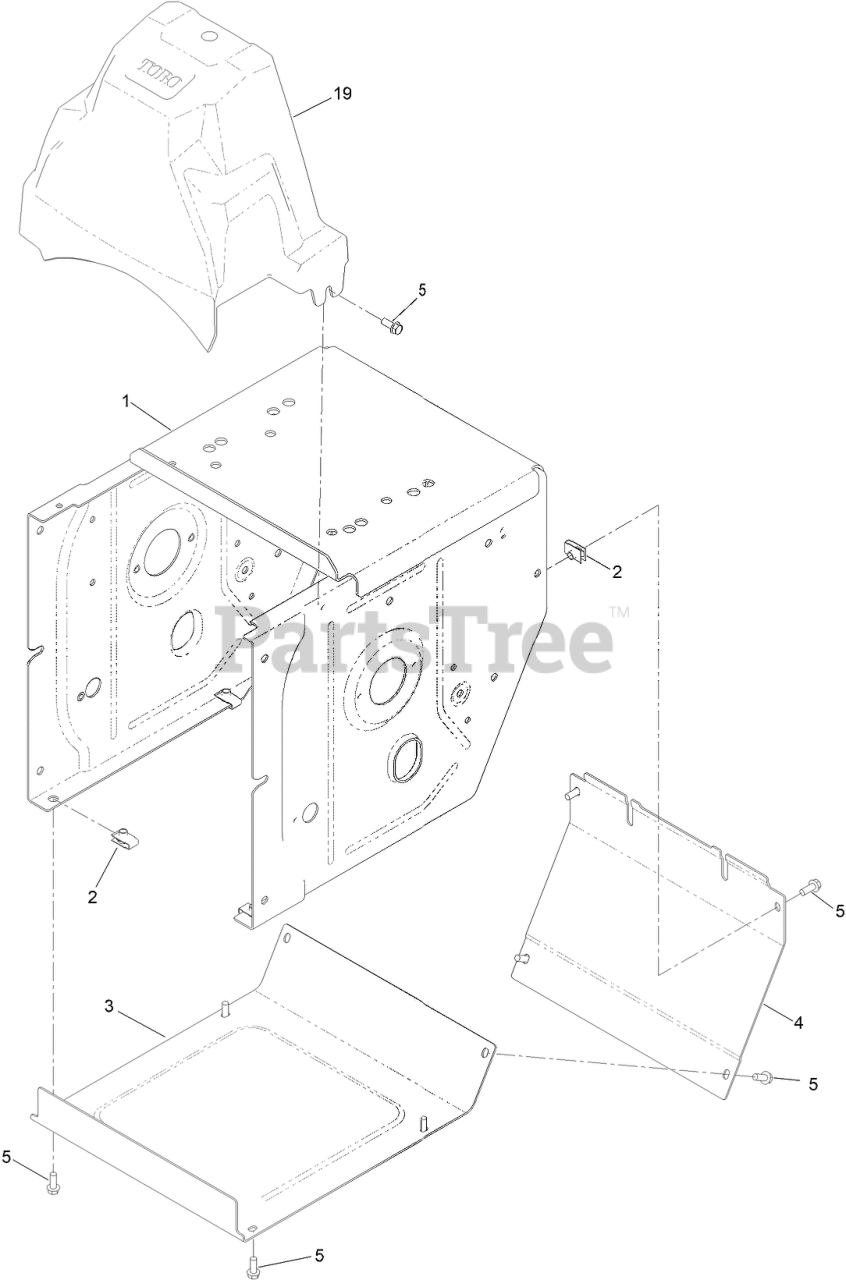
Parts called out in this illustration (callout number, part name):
1	FRAME-TRACTION
3	COVER-BOTTOM
4	COVER-REAR
5	SCREW-HWH
19	BELT COVER, NO LIGHT
